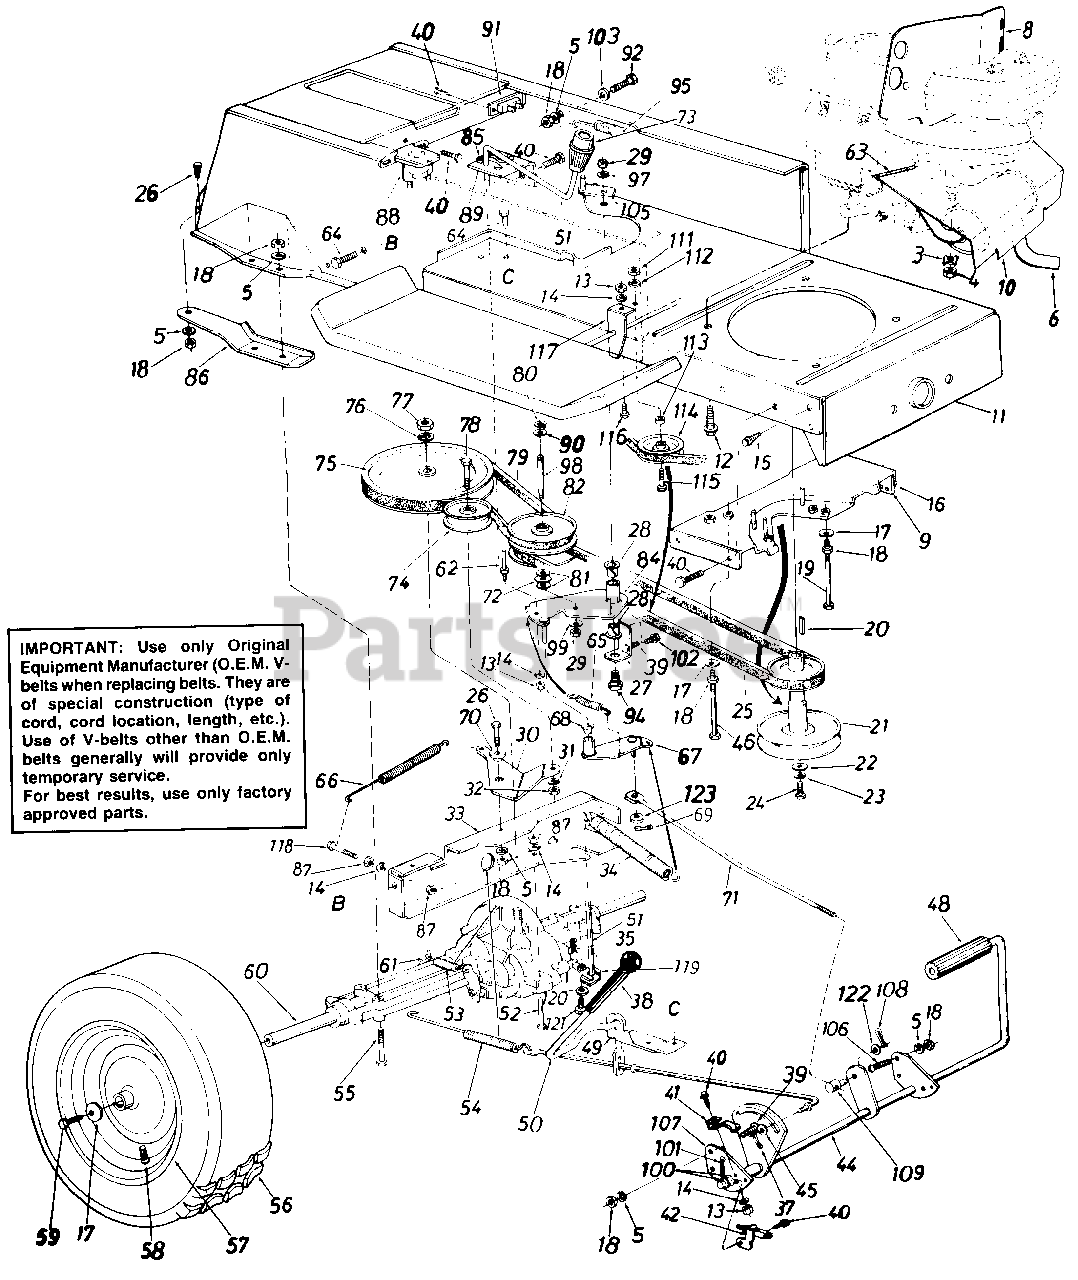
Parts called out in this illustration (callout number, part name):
3	Special L-Wash. 5/16" I.D.
4	Hex Nut 5/16-18 Thd.
5	L-Wash. 5/16" I.D.
6	Exhaust Muffler
8	Top Heat Shield
9	Brake Cable Brk't.
10	Front Heat Shield
11	Lower Frame Ass'y.
12	Hex Wash. Hd. TT-Tap Scr. 3/8-16 x 1.25" Lg.
13	Hex Nut 1/4-20 Thd.
14	L-Wash. 1/4" I.D.
15	Hex Wash. Hd. AB-Tap Scr. 5/16" x.75" Lg.
16	Belt Guard Brkt. Ass'y.
17	Bell-Wash. .345" I.D. x .88"
18	Hex Nut 5/16-18 Thd.
19	Hex Bolt 5/16-18 x 4.00"
20	Sq. Key 1/4" x 1/4" x 2.00"
21	Engine Pulley
22	Fl-Wash. 7/16" I.D. x 1.25"
23	L-Wash. 7/16" I.D.
24	Hex Bolt 7/16-20 x 1.50" Lg.
25	Variable-Speed Belt
26	Hex Bolt 5/16-18 x .75" Lg.
27	Bearing Shaft Bracket Ass'y.
28	Flanged Nyliner Brg. 518" I.D. x .88" Lg.
29	Hex Nut 3/8-24 Thd.
30	Idler Bracket
31	L-Wash. 3/8" I.D.
32	Hex Nut 3/8-24 Thd.
35	Inter. Cotter Pin
37	Cotter Pin 3/32" Dia. x .75"
39	Truss Mach. Scr. 5/16-18 x .75" Lg.
40	Hex Wash. Hd. Self-Tap Scr. 1/4-20 x .50" Lg.
41	Switch Actuator
42	Safety Switch
44	Clutch & Brake Pedal Ass'y.
45	Fl-Wash.
46	Hex Bolt 5/16-18 x 4.5"
48	Foot Pad
49	Brake Lever Bracket
50	Hill Holder Brake Handle
51	Shift Lever Ass'y.
52	Hex Bolt 1/4-28 x 1.75" Lg.
53	Ext. Spring .38" O.D. x 2.5"
54	Ext. Spring .59" O.D. x 7.08"
55	Hex Bolt 5/16-18 x 2.75"
58	Air Valve
59	Hex Bolt 5/16-24 x .75" Lg.
60	Transaxle Complete-R.H.
61	Brake Return Spring Anchor
62	Belt Guard Pin 1/4-20 Thd.
64	Hex Wash. TT-Tap Scr. 5/16 x .62" Lg.
65	Ext. Spring
66	Ext. Spring .62" O.D. x 6.1 2"
68	Flanged Bearing
69	Cotter Pin 3/32" Dia.
70	Shoulder Spacer .500" Dia. x.27" Lg.
71	Speed Control Link
72	Truss Bearing .56 Dia. x 1.25"
73	Knob
74	Fl-ldler Pulley 3.25" x .75"
75	1/2" "V"-Pulley 8.0" O.D. x .501 " I.D.
76	L-Wash. 1/2" I.D.
77	Hex Jam Nut 1/2-20 Thd.
78	Hex Bolt 3/8-24 x .75" Lg.
79	Variable Speed Belt
80	Snap Ring .56" Dia.
82	Variable Speed Pulley Ass'y. 5" O.D.
86	Axle Support Brkt.-R.H.
87	Hex Nut 1/4-28 Thd.
88	Solenoid
89	Shift Lever Bracket
90	Teflon Washer
91	Circuit Breaker
92	Hex Bolt 5/16-18 x 1.50"
94	Shld. Bolt 3/8-24 x 3.12" Lg.
95	Ext. Spring .99" O.D. x 11.0"
97	Bell-Wash. .38" I.D. x .88"
98	Shaft .56" Dia. x 3.875" Lg.
99	Bell-Wash. .39" I.D. x 1.12"
100	Fl-Wash.
101	Cotter Pin 3132" Dia. x .75
102	Hex Wash. Hd. Scr. 5/16-18 0 x.62" Lg.
103	Fl-Wash. .34" I.D. x 1.12" O.D.
105	Belt Guard
106	Hex Bolt 5/16-18 x .75" Lg.
107	Pedal Bracket
108	Cotter Pin 3/32 x .75"
109	Ferrule
111	Hex Nut 3/8"-16 Thd.
112	L-Wash. 3/8" I.D.
113	Fl-Wash. .390" I.D. x 1.12"
114	Fl-ldler w/Flanges 2.750
115	Hex Bolt 3/8-16 x 2.00" Lg.
116	Hex Bolt 1/4-20 x .62" Lg.
117	Spring Hanger Bracket
118	Hex Bolt 1/4-28 x 1.25" Lg.
119	Shift Lever Link Ass'y.
120	Bell-Wash. .265 I.D. x .75 O.D.
121	Hex Bolt 1/4-28 x .62" Lg.
122	Fl-Wash. .385" I.D. x .62" O.D.
123	Fl-Wash. .34" I.D. x .68" O.D.
